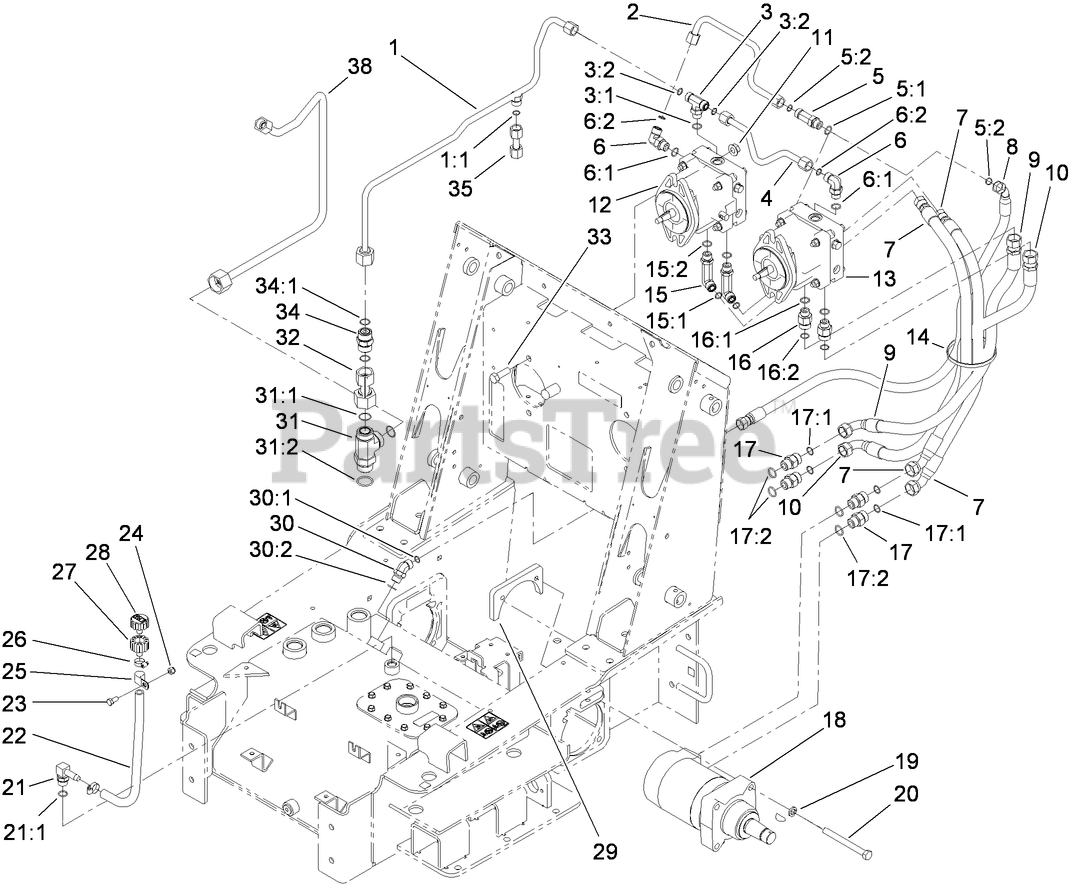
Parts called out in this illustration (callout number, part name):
1	HYD TUBE ASM
1:1	O-RING
2	TUBE-HYD
3	FITTING-HYD, TEE
3:1	O-RING
3:2	O-RING
4	TUBE-HYD
5	FITTING-TEE
5:1	O-RING
5:2	O-RING
6	FITTING-ELBOW-90 DEG
6:1	O-RING
6:2	O-RING
7	HOSE-HYD
8	HOSE-HYD
9	HOSE-HYD
10	HOSE-HYD
11	NUT-HF
12	RH HYD PUMP ASM
13	LH HYD PUMP ASM
14	TIE-CABLE
15	FITTING-ELBOW, 90 DEG
15:1	O-RING
15:2	O-RING
16	FITTING-STR
16:1	O-RING
16:2	O-RING
17	FITTING-STRAIGHT
17:1	O-RING
17:2	O-RING
18	HYD MOTOR ASM
19	WASHER-LOCK
20	SCREW-HH, TAP
21	FITTING-ELB 90
21:1	O-RING
22	HOSE-VENT
23	SCREW-HHF
24	NUT-LOCK, NI
25	CLAMP-R
26	CLAMP-HOSE
27	ADAPTER-BREATHER
28	BREATHER
29	PLATE-MOUNTING
30	FITTING-HYD, 45 DEG
30:1	O-RING
30:2	O-RING
31	FITTING-TEE
31:1	O-RING
31:2	O-RING
32	TUBE-HYD
33	SCREW-HH
34	HYD CHECK VALVE ASM
34:1	O-RING
35	TUBE-HYD
38	HYD TUBE ASM
